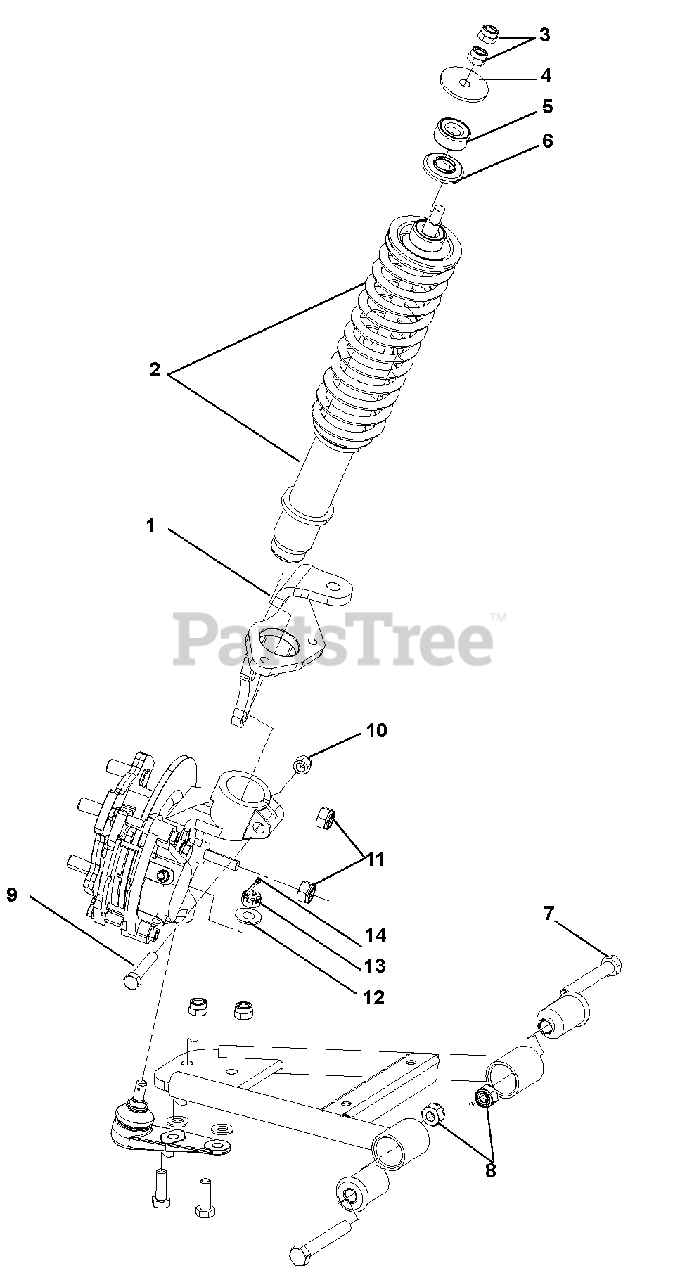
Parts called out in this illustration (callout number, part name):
1	STEERING BRACKET RIGHT
2	STEERING BRACKET LEFT
3	STRUT/COIL SPRING
4	NUT HEX JAM M10X1,25 6MTHK YLW
5	WASHER FLT 1.92ODX.413IDX.118T
6	GROMMET, RUBBER MOUNT
7	WASHER, STRUT MOUNT
8	HHCS M12X1.75X80 GR8.8 PLT
9	@NUT-LK-NYL M12-1.75 YWZC
10	BLT-HEX .38-16X2.00 GR8 YWZC
11	@NUT-LK-NYL .38-16 YWZC
12	NUT-LK-NYL M10-1.5 YWZC
13	@WSHR-FL-STL.438X1.00X.083 YWZ
14	NUT-HEX-SLOTTED M10-1.25 YWZC
15	@PIN-CTR .09X1.00 EXTPRSQCT YZ
